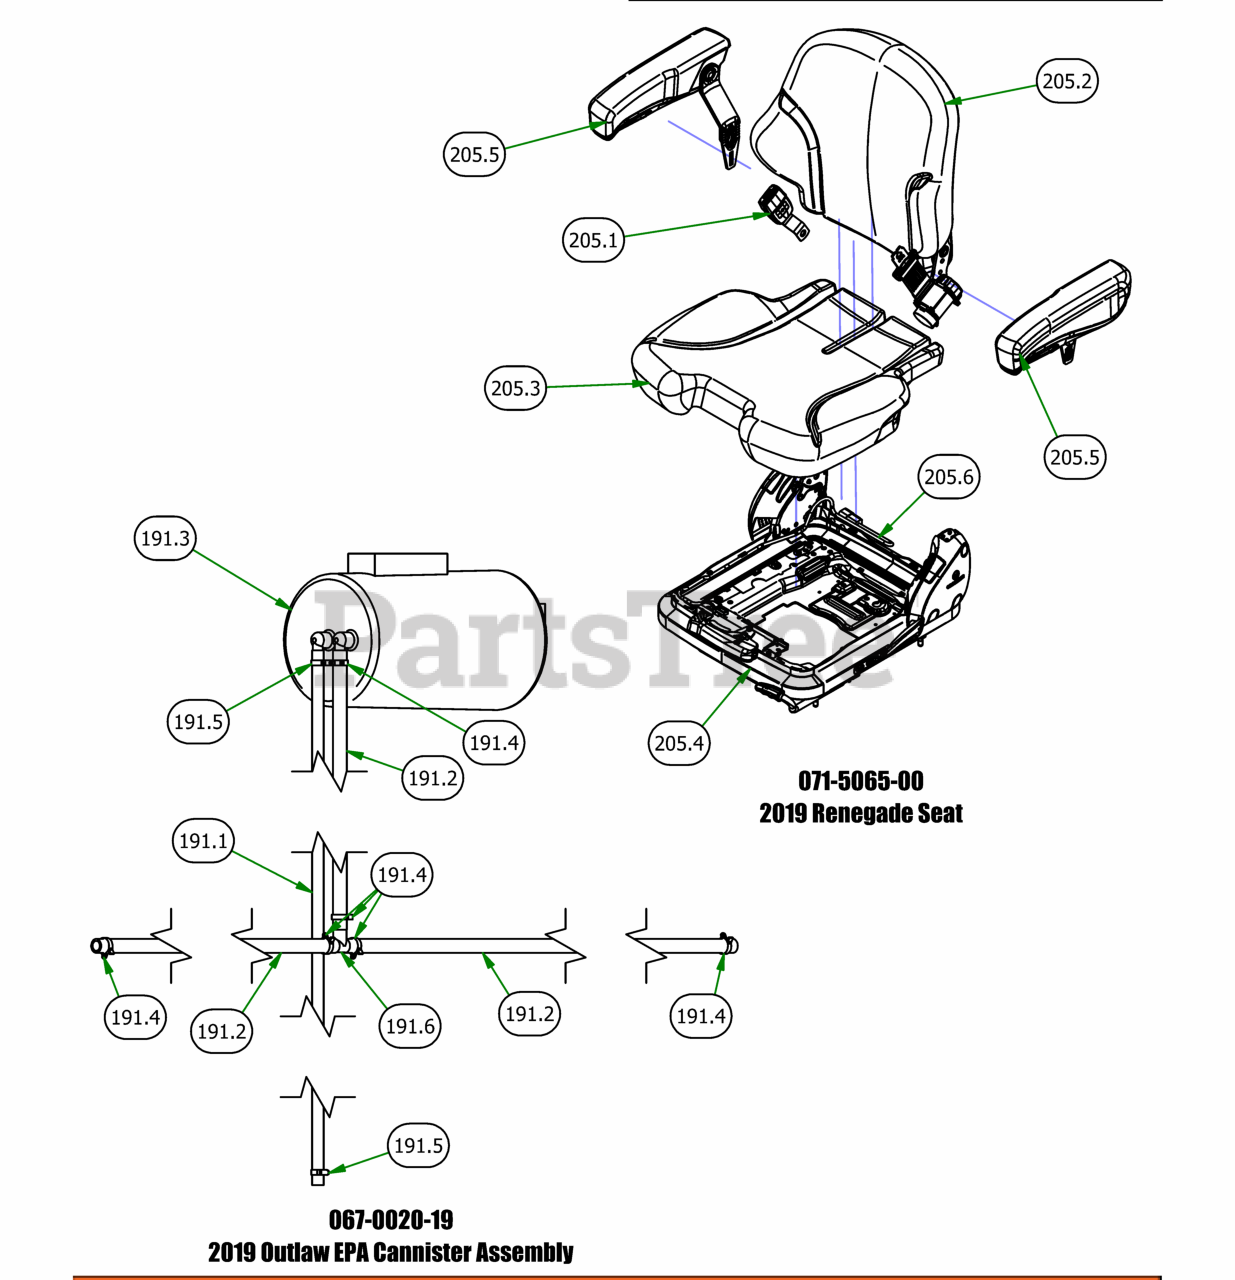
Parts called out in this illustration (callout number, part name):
191.1	3/16" Vinyl Tubing, 66" Long
191.2	1/4" Vinyl Tubing 38" Long
191.3	Carbon Canister
191.4	3/16 Vinyl Clamp
191.5	3/16" Vinyl Hose Clamp
191.6	fuel line T
205.2	Backrest Cushion
205.3	Seat Cushion
205.4	Slave & Adjuster
205.5	Arm Rest Kit
205.6	Seat Switch
